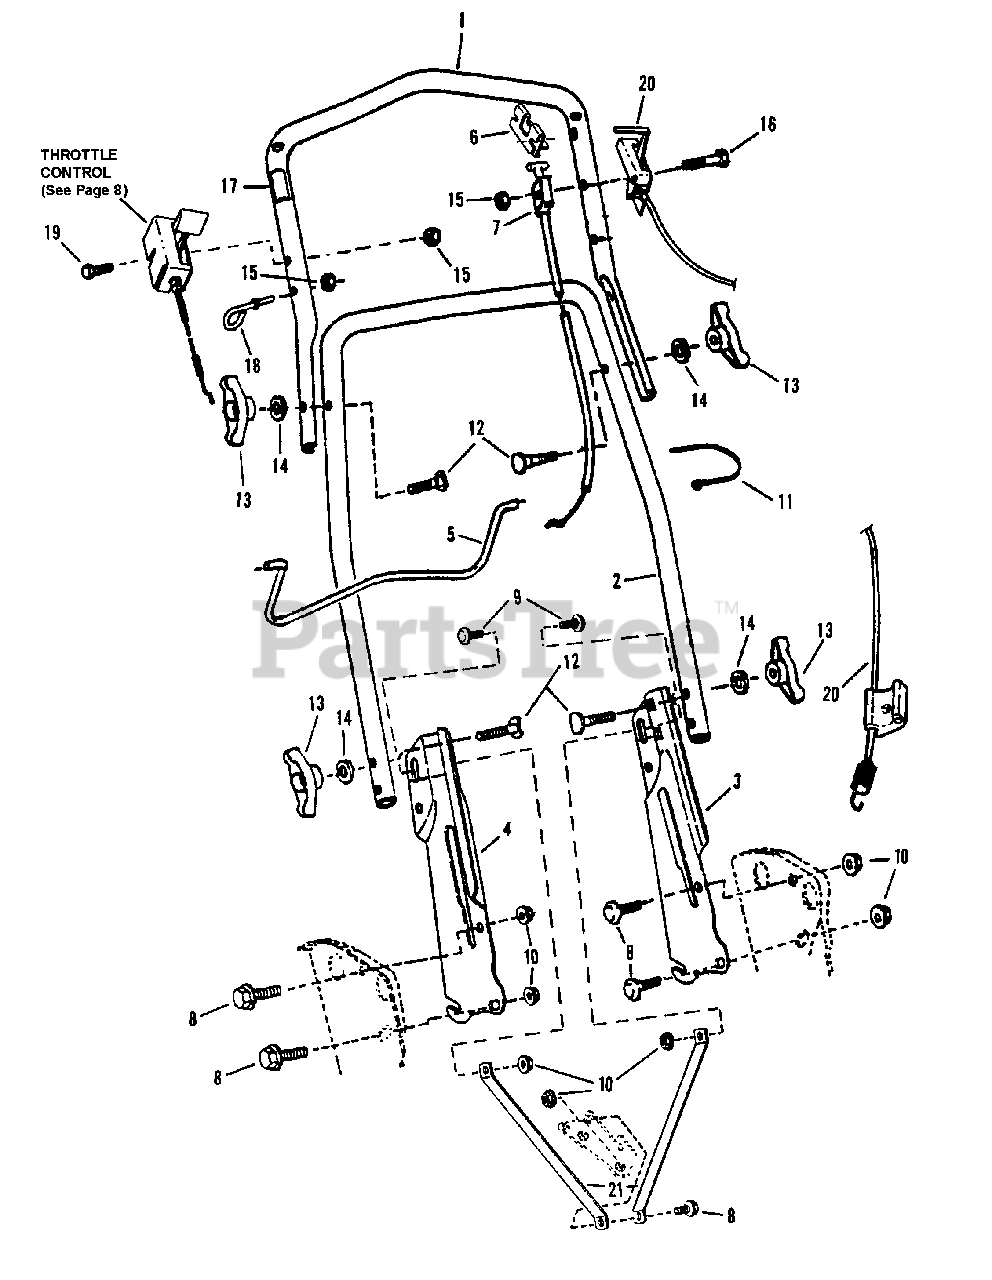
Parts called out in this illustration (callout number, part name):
1	HANDLE, Upper
2	HANDLE, Middle
3	HANDLE, Lower Left Hand
4	HANDLE, Lower Right Hand
5	BAIL, OPC Control (12.5" Wide)
6	CLIP, Blade Control
7	CABLE, Blade Control (52-13/16")
8	BOLT, 5/16-18 x 3/4" Flange Lock, Grade 5
9	BOLT, 5/16-18 x 5/8" Carriage, Grade 5
10	NUT, 5/16-18 Hex Flange Lock, Grade 5
11	TIE, Wire
12	SCREW, 5/16-18 x 1-7/8 Curved Head, Grade 2
13	T-KNOB, 5/16-18
14	WASHER, 5/16 Internal Tooth Lock
15	NUT, 1/4-20 Hex, Grade 5 or B
16	SCREW, 1/4-20 x 2" Hex Cap, Grade 5
17	DECAL, Blade Control (R.H. Side)
18	GUIDE, Rope
19	SCREW, 1/4-20 x 1-1/2" Hex Cap, Grade 5
20	CABLE, Swivel Lock
21	BRACES, Handle
